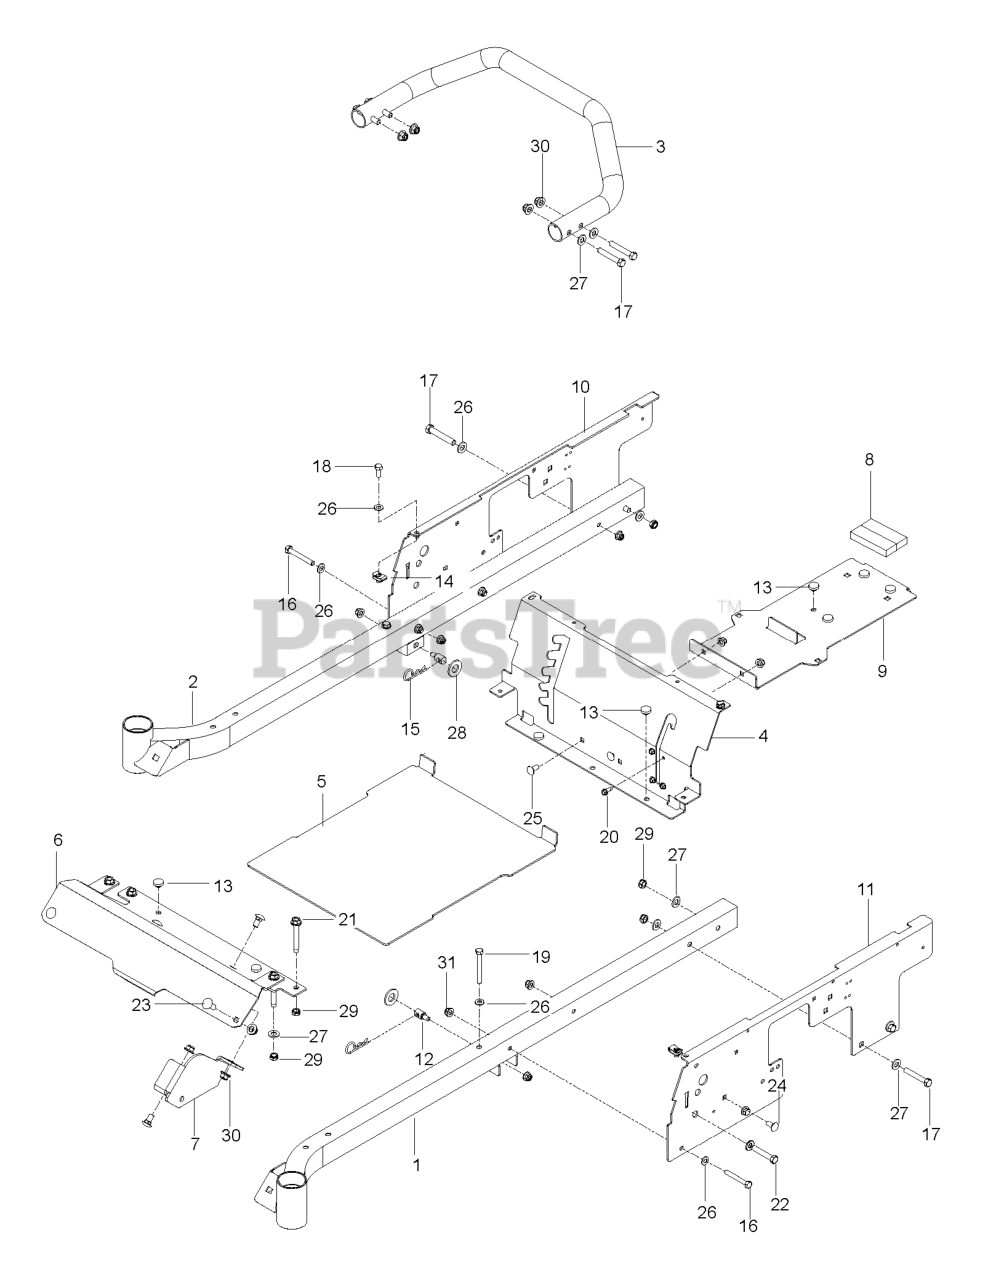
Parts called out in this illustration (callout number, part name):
1	FRAME TUBE, LH, ORG
2	FRAME TUBE, RH, ORG
3	IMPACT BAR, ORG
4	PANEL.SEAT.SUPPORT.ORANGE
5	PAN, FLOOR W/DECALS, HUS
6	FOOT REST, ORG
7	BRACKET, FRONT DECK, BLK
8	FOAM STRIP, FUEL TANK
9	SUPPORT, TANK/BATT, BLK
10	PLATE.RH.SIDE.ORANGE
11	PLATE.LH.SIDE.ORANGE
12	STUD.FASTNER.W/ANTI-ROTATE
13	GROMMET, BUMPER
14	U-CLIP 5/16-18 NUT RETAINER
15	HAIRPIN #4
17	HCS 3/8C X 2 1/4
18	HCS 5/16C X 3/4
19	HCS 5/16C X 2-3/4
20	SCREW 1/4 X 5/8
21	ENGINE BOLT, SPECIAL
22	HCS 1/2C X 2 3/4
23	RHSNB 3/8C X 1
24	RHSNB 3/8-16 X 3/4 GR5 ZD
25	BOLT 5/16C X 3/4" CARRIAGE
26	FLAT WASHER 5/16 SAE
27	WASHER 3/8 SAE FLAT
28	WASHER 5/8 FLAT
29	NUT HEX 3/8-16 NYLON, THIN
30	NUT 3/8-16 HEX FLG NYLOC ZD
31	5/16-18 NYLOC FLANGE NUT
